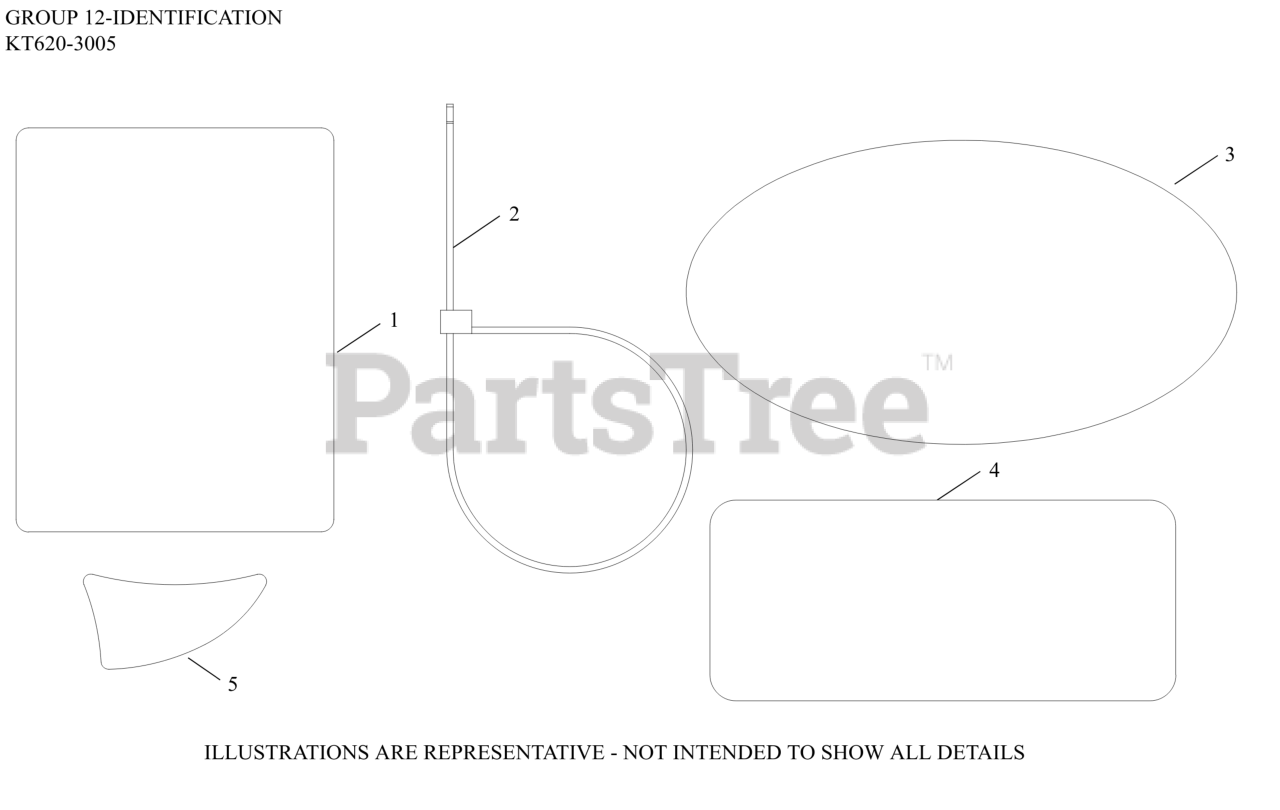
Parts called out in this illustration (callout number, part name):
1	LABEL, CLEAR LAMINATION
3	LABEL, 6600 SERIES (21HP)
3	LABEL, PRO PERFORMANCE FILTRATION SYSTEM
4	LABEL, CANADIAN COMPLIANCE
5	LABEL, SMART CHOKE
